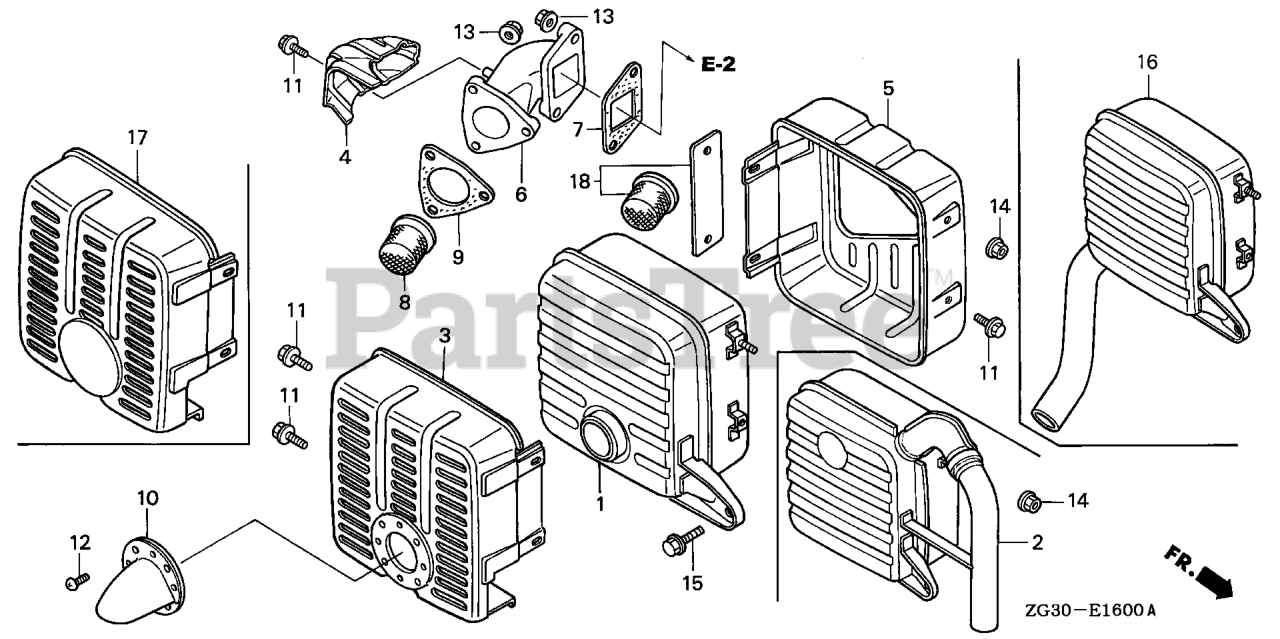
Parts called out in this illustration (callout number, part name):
1	MUFFLER
3	PROTECTOR A, MUFFLER
5	PROTECTOR B, MUFFLER
6	PIPE, EX.
7	GASKET, EX. PIPE (NON-ASBESTOS)
9	GASKET, MUFFLER (NON-ASBESTOS)
10	DEFLECTOR, MUFFLER
11	BOLT, FLANGE (5X8)
12	SCREW, PAN (5X8)
13	NUT, FLANGE (8MM)
14	NUT, FLANGE (8MM)
15	BOLT, FLANGE (8X20) Use up to Engine SN 1609606.
18	ARRESTER KIT, SPARK
